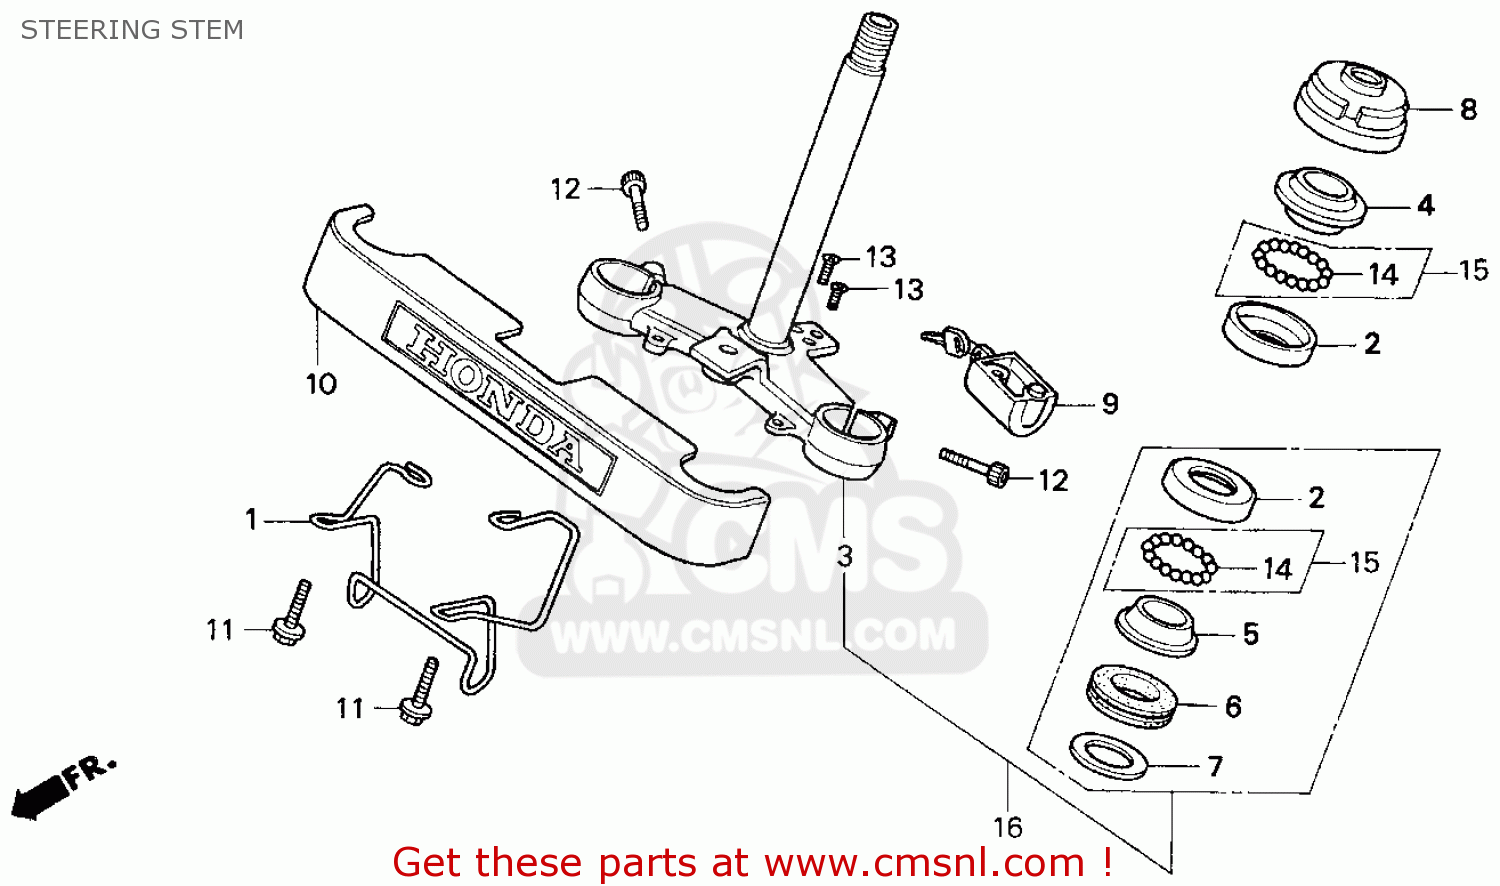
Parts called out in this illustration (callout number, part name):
1	CLAMP,FR BRK HOSE
2	RACE,STRG.BALL
3	STEM COMP.,STRG.
4	RACE,STRG.TOP CON
5	RACE STRG.BOTTOM
6	DUST-SEAL
7	WASHER, DUSTSEAL
8	THREAD HEAD TOP
9	LOCK,STRG.HANDLE
10	COVER,FRONT
11	BOLT,FLANGE,6X20
12	BOLT SOCKET
13	SCREW, CROSS 6X12
14	BALL,STEEL.,6
